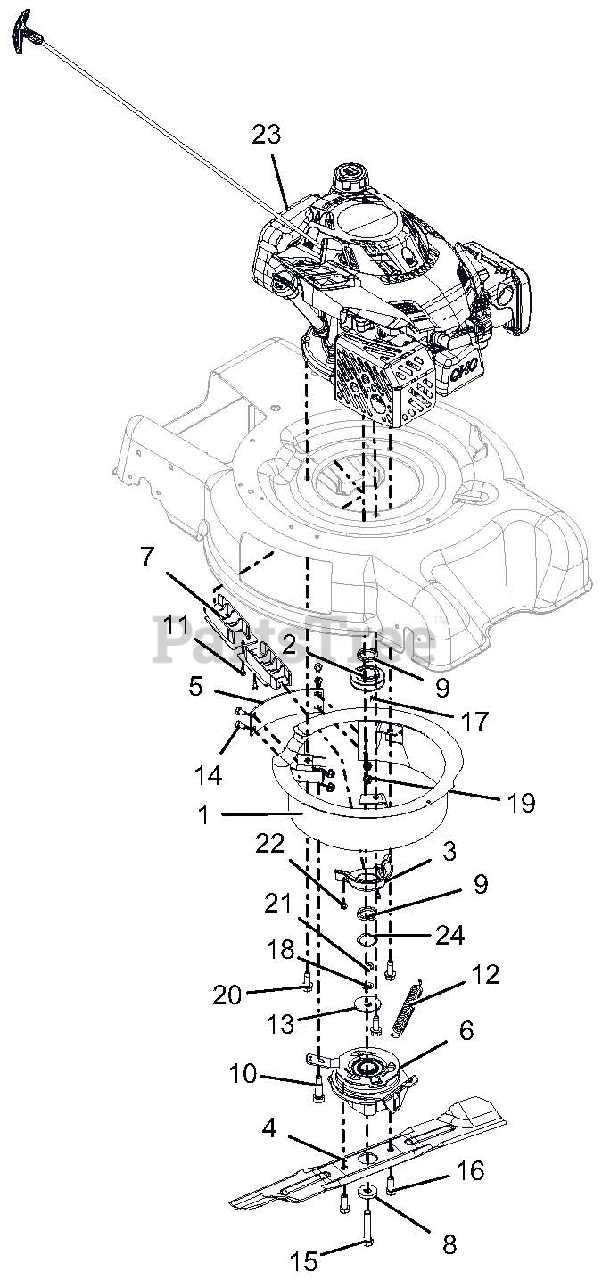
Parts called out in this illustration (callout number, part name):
1	WLDMT, ENCLOSURE - BBC
2	PULLEY, GROUND DRIVE, LM
3	GUIDE, BELT CRANK
4	BLADE, MOWER 21" HIGH LIFT-BBC
5	BAFFLE, BBC
6	CLUTCH, RAZOR/XD3, 25MM
7	GUIDE, BELT INNER
8	WSHR-FL-STL .44X1.25X.25 YWZC
9	SPCR, 1.00 X 1.375 X .179
10	BLT,SHLDR 12MM X 25 W/ M10 THD
11	SCR-TAP 10-24X.375 PRE-COAT 80
12	SPRING, EXTENSION BBC
13	WSHR-FL-STL .469X1.75X.10 YWZC
14	@BLT-HEX .25-20X.50 GR5 YWZC
15	@BLT-HEX .4375-20X2.25 GR8 YWZ
16	BLT-HEX M10 X 1.5X25 YWZC
17	KEY-SQ .188X.188X.375
18	WSHR-FL-STL .45X.75X.033
19	@NUT-LK-TOP-FLG .25-20 YWZC
20	@SCR-TAP .38-16X1.00 HWH TR YZ
21	WSHR-FL-STL .459X.750X.105 YZC
22	SCR-TAP 10-24X.25 CRSLPH TR YZ
23	ENGINE, SUBARU 175CC VERT. BBC
24	WASHER - WAVE 1.09X1.37X.016
